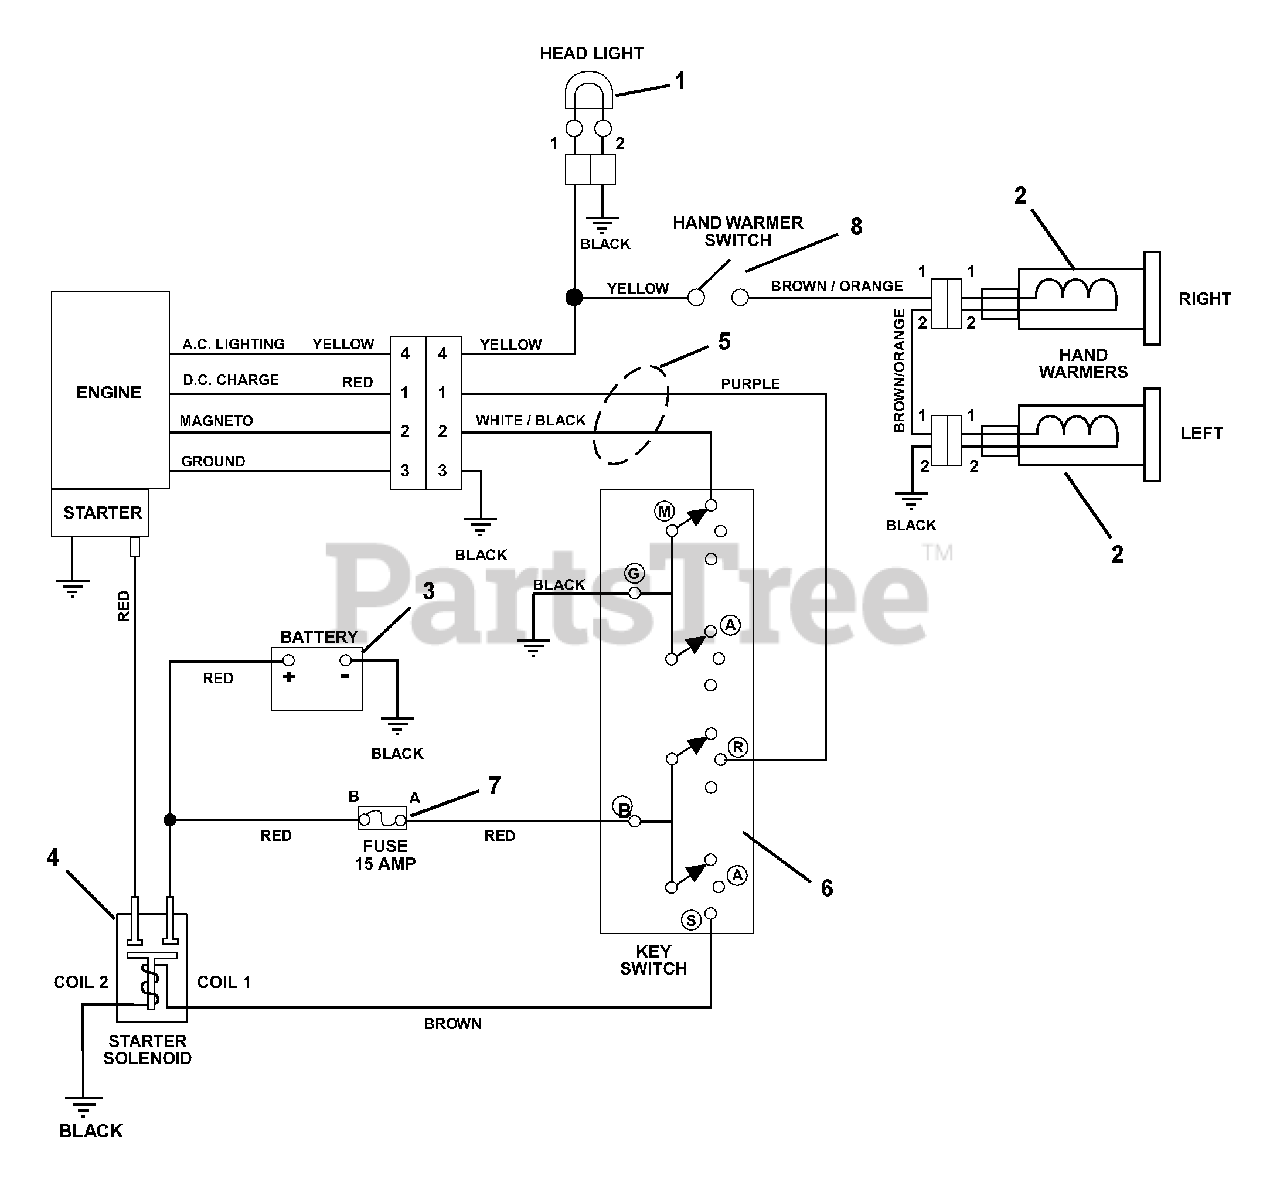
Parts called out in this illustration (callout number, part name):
1	LIGHT, HALOGEN ASSY.
2	WARMER, HAND W/TERMINAL
4	SOLENOID
5	HARNESS, WIRE-LT, HW, 12V
6	SWITCH ASSEMBLY
7	FUSE, 15 AMP.
8	SWITCH, ON/OFF
